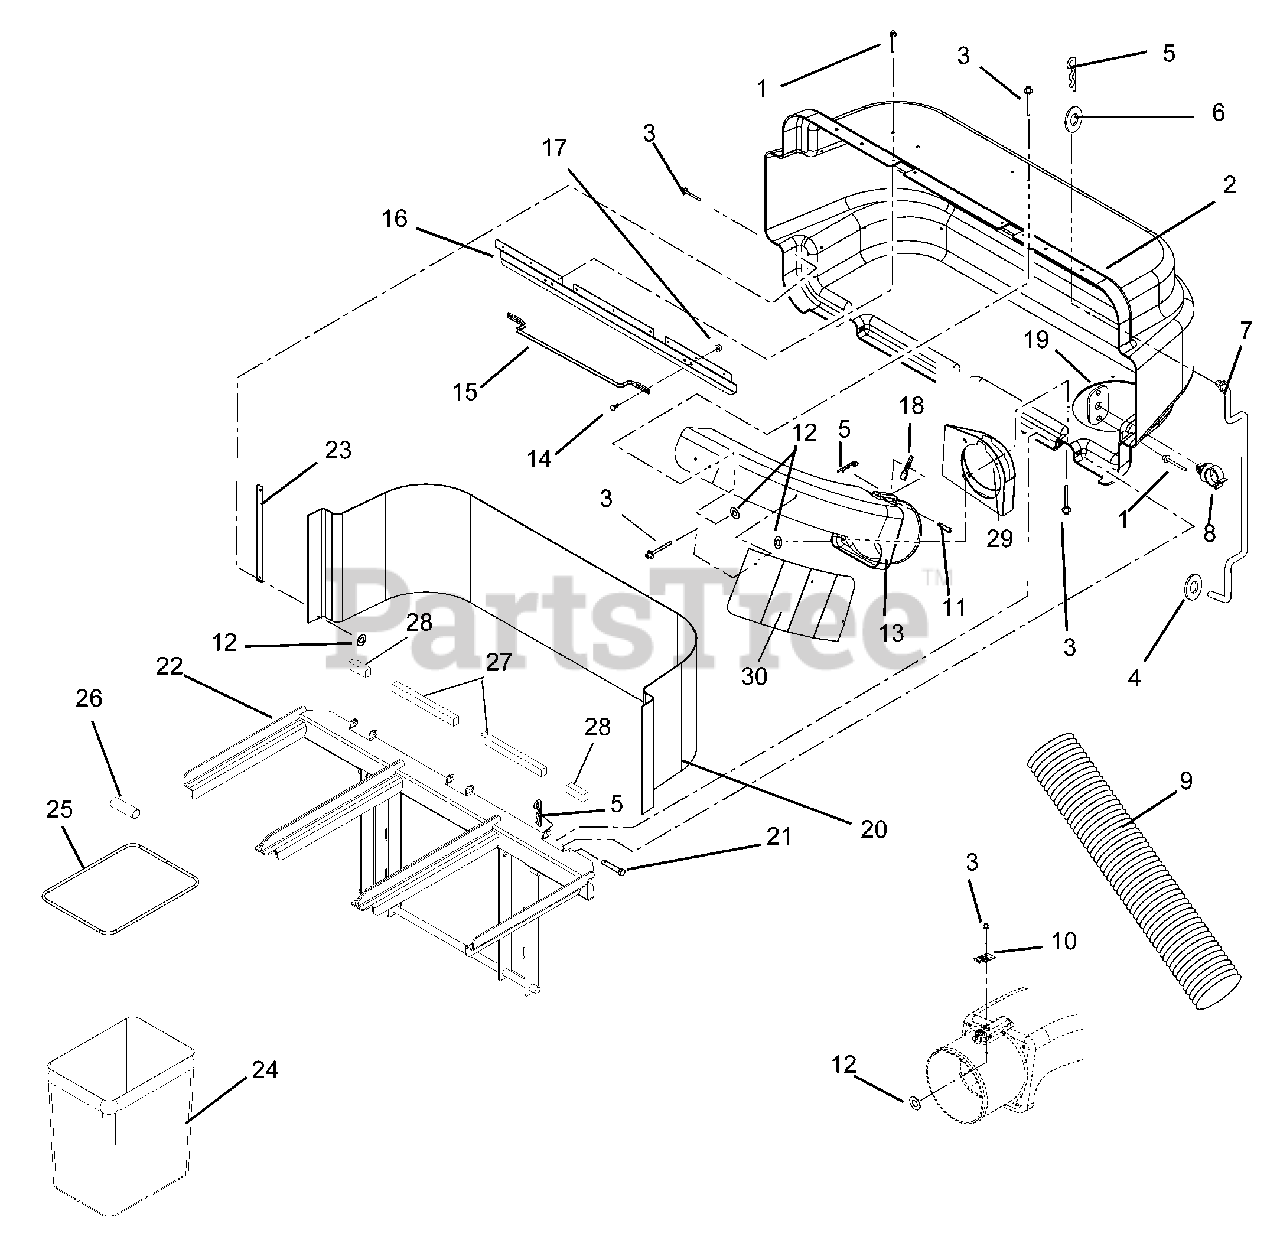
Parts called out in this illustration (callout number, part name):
1	Rivet, Pop .187 x .402
2	Cover, Bagger with Decal
3	Rivet, Pop .187 x .527
4	Retainer, .38 Push-On
5	Pin-Hair
6	Washer-Flat-Steel .046 x .812 x .065
7	Prop Rod, Bagger
8	Clip .38
9	Hose, 7 x 63 Kanaflex 165 Clear
10	Thumb Latch
11	Pin, Clevis .31 x 2.62 Grade 5
12	Washer-Flat-Steel .219 x .50 x .049
13	Boot, Upper
14	Bolt, Round Head Square Neck .25-20 x .75 Grade 5
15	Bagger Handle
16	Latch, Cover
17	Nut, Locking-Top-Flange .25-20
18	Indicator, Flow
19	Plate, Rod Clip
20	Screen, Bagger
21	Pin, Clevis .368/.373 x 3.25
22	Weldment, Bagger Frame
23	Strap, Cover
24	Bag, Mesh
25	Frame, Bag
26	Hose, .38 x .50 x 3.00 Vinyl
27	Grass Block, 10.5-In. Foam
28	Grass Block, 4-In. Foam
29	Hose Support Insert
30	HD Bagger Deflector
